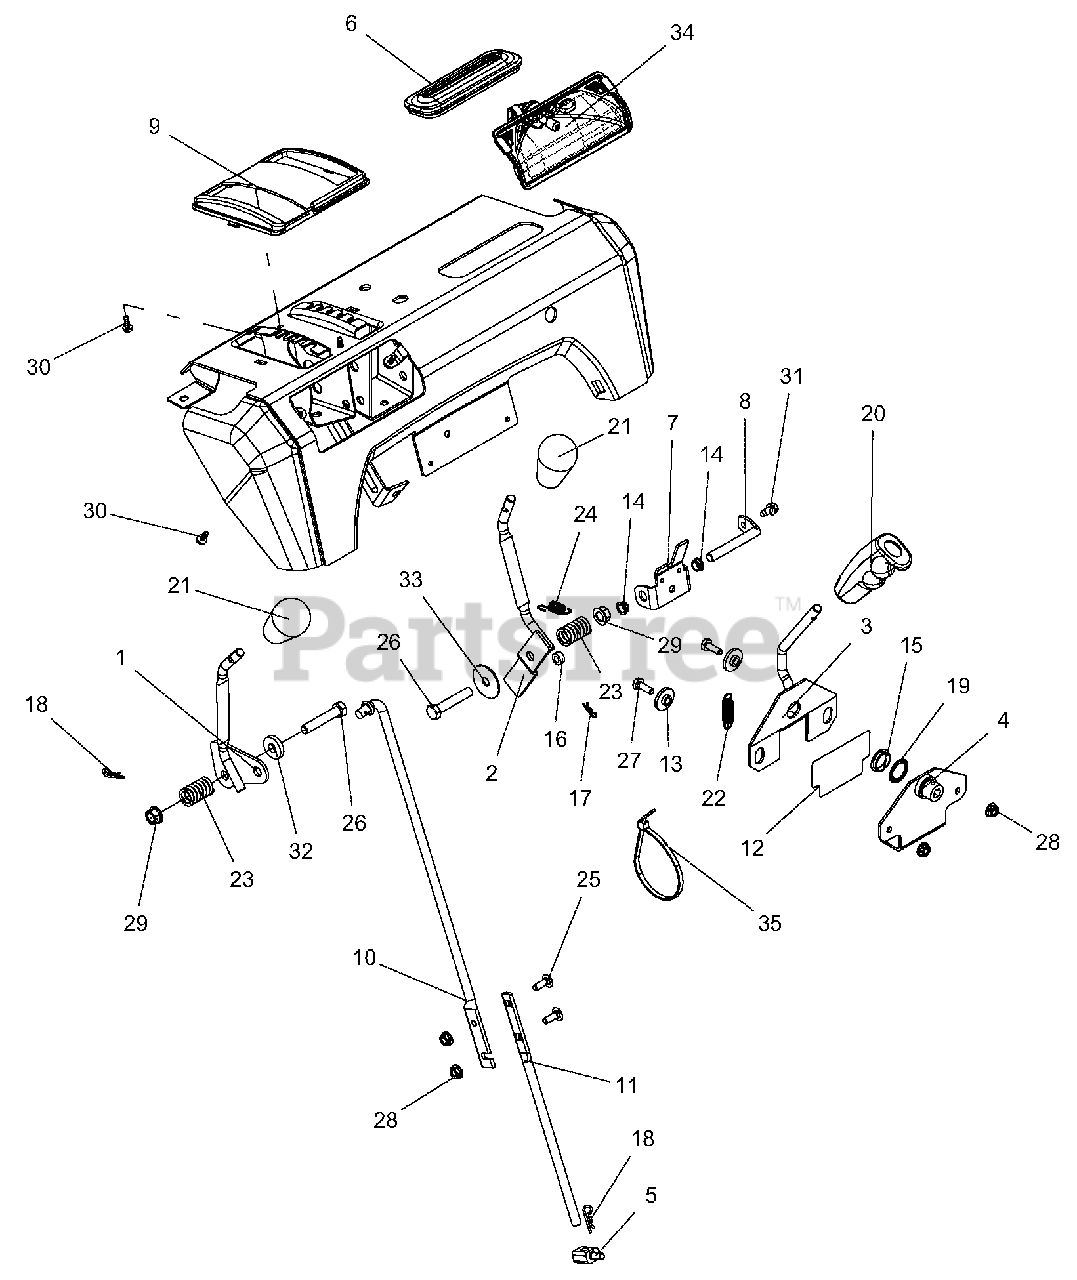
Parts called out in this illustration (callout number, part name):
1	WELDMENT, CONTROL LEVER(SHIFT)
2	WELDMENT, CONTROL LEVER (DEFL)
3	LEVER, CHUTE CONTROL
4	MOUNT, CHUTE CONTROL
5	PIVOT,SHIFT ROD .375-16(TRUNN)
6	GROMMET-BOOT, QUICKTURN
7	BRACKET, INTERLOCK ARM
8	ROD, PIVOT - INTERLOCK
9	BEZEL, SHIFT
10	ROD, SHIFT - UPPER
11	ROD, SHIFT - LOWER
12	TAPE, DIE CUT - QUICK TURN
13	BSHG-FLG .265X.448X.243X1.00
14	BUSHING, POLYLINER-.38 SNAPIN
15	BUSHING, POLYLINER-.75 SNAPIN
16	BSHG-SLV .265X.500X.219
17	PIN-HAIR INT .06X.18X.77
18	PIN-HAIR INT .08X.18X1.18 YWZC
19	NUT, PUSH -.75" SHAFT
20	CONTROL HANDLE, QUICK TURN
21	KNOB,SOFT TEARDROP,PUSH-ON GRY
22	SG-TENS .048X.44X1.75 WLD 9
23	SG-COMP .125X.781X1.250
24	SPRING-EXT .047X.438X1.45
25	@BLT-RDHDSQNK .25-20X.75 G5YZ
26	@BLT-HEX .38-16X2.00 GR5 YWZC
27	@BLT-HEX .25-20X.75 GR5 YWZC
28	@NUT-LK-CTR-FLG .25-20 YWZC
29	@NUT-LK-TOP-FLG .38-16 YWZC
30	SCR-TAP #10X.50 BOSS INDHXHD
31	SCR-TAP .25-20X.50 HWH TR YWZ
32	WSHR-FL-STL .406X1.00X.188 YWZ
33	WSHR-FL-STL .380X1.50X.062 YWZ
34	HEADLIGHT ASSY, HALOGEN 20W
35	CABLE TIE LG 5-1/2
